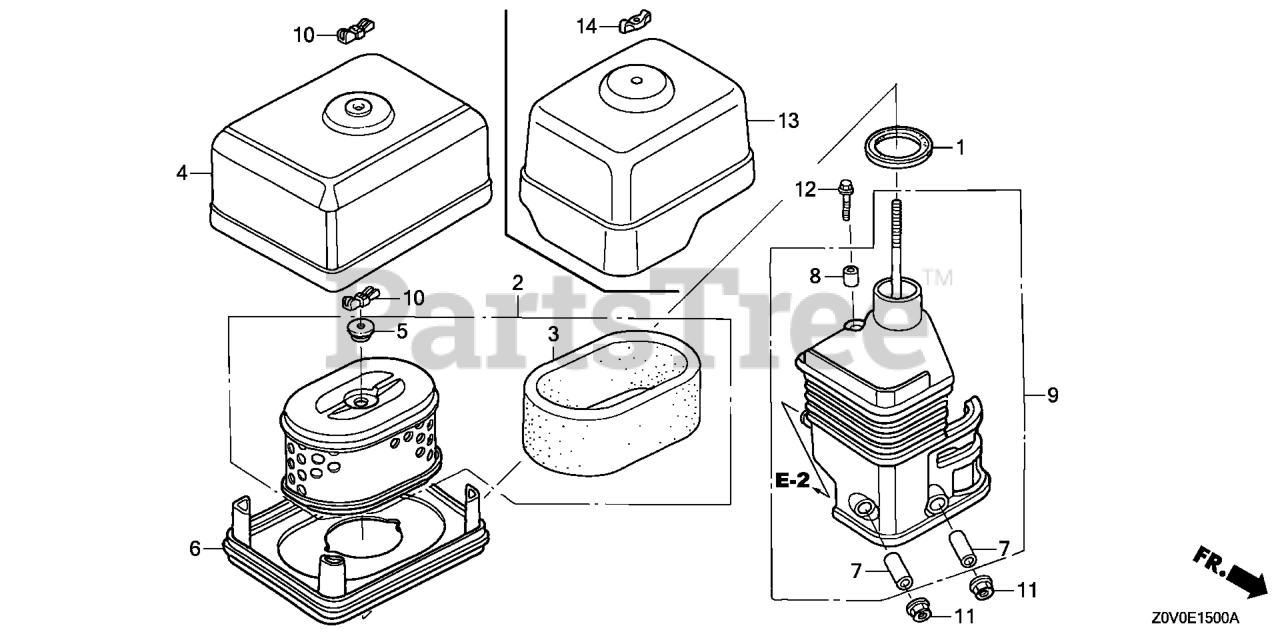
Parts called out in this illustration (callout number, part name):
1	GASKET, ELBOW
2	ELEMENT, AIR CLEANER (DUAL)
3	FILTER (OUTER)
5	GROMMET, AIR CLEANER
6	NOSE, MUFFLER
7	COLLAR, AIR CLEANER Use from Engine SN 1786085.
8	COLLAR B, AIR CLEANER
9	ELBOW, AIR CLEANER
10	WINGNUT, TOOL BOX SETTING
11	NUT, FLANGE (6MM)
12	BOLT, FLANGE (6X20)
13	COVER, AIR CLEANER
14	NUT, AIR CLEANER
